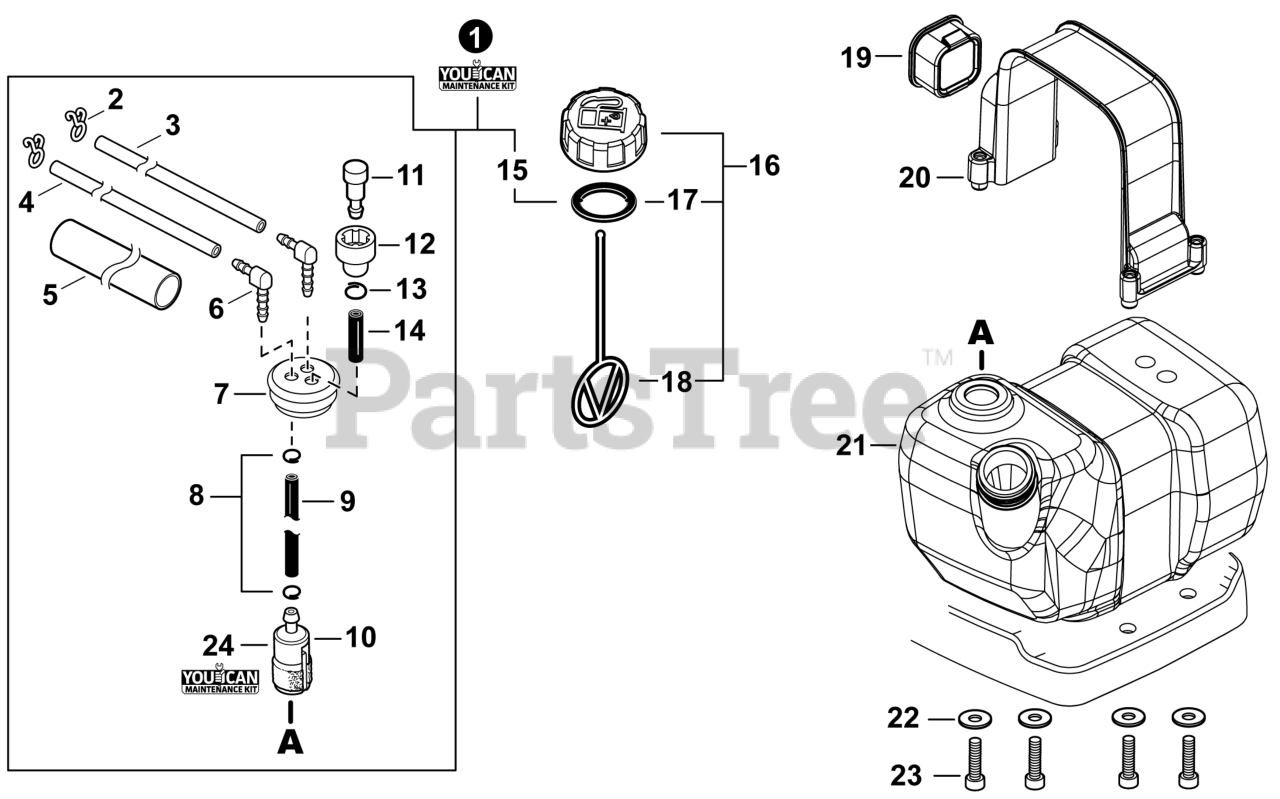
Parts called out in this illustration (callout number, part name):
1	FUEL SYSTEM KIT - YOUCANT
2	CLIP, SPRING 5.2
3	PIPE, FUEL 3x6x170 YELLOW
4	PIPE, FUEL 3.5x6x160 CLEAR
5	TUBE, INSULATOR 16x18x90
6	CONNECTOR, PIPE
7	GROMMET, FUEL
9	PIPE, FUEL 3x5x210 BLACK
10	FILTER, FUEL
11	VENT ASSY
12	HOLDER, VENT
13	CLIP 6.5 MM
14	PIPE, FUEL 3x6x30 BLACK
15	GASKET, FUEL CAP
16	CAP ASSY, FUEL
17	GASKET, FUEL CAP
18	CONNECTOR, CAP L= 123
19	CUSHION
20	BAND, FUEL TANK
21	TANK, FUEL
22	WASHER 5.5x16x0.8
23	BOLT 5x20
24	TUNE-UP KIT - YOUCANT
